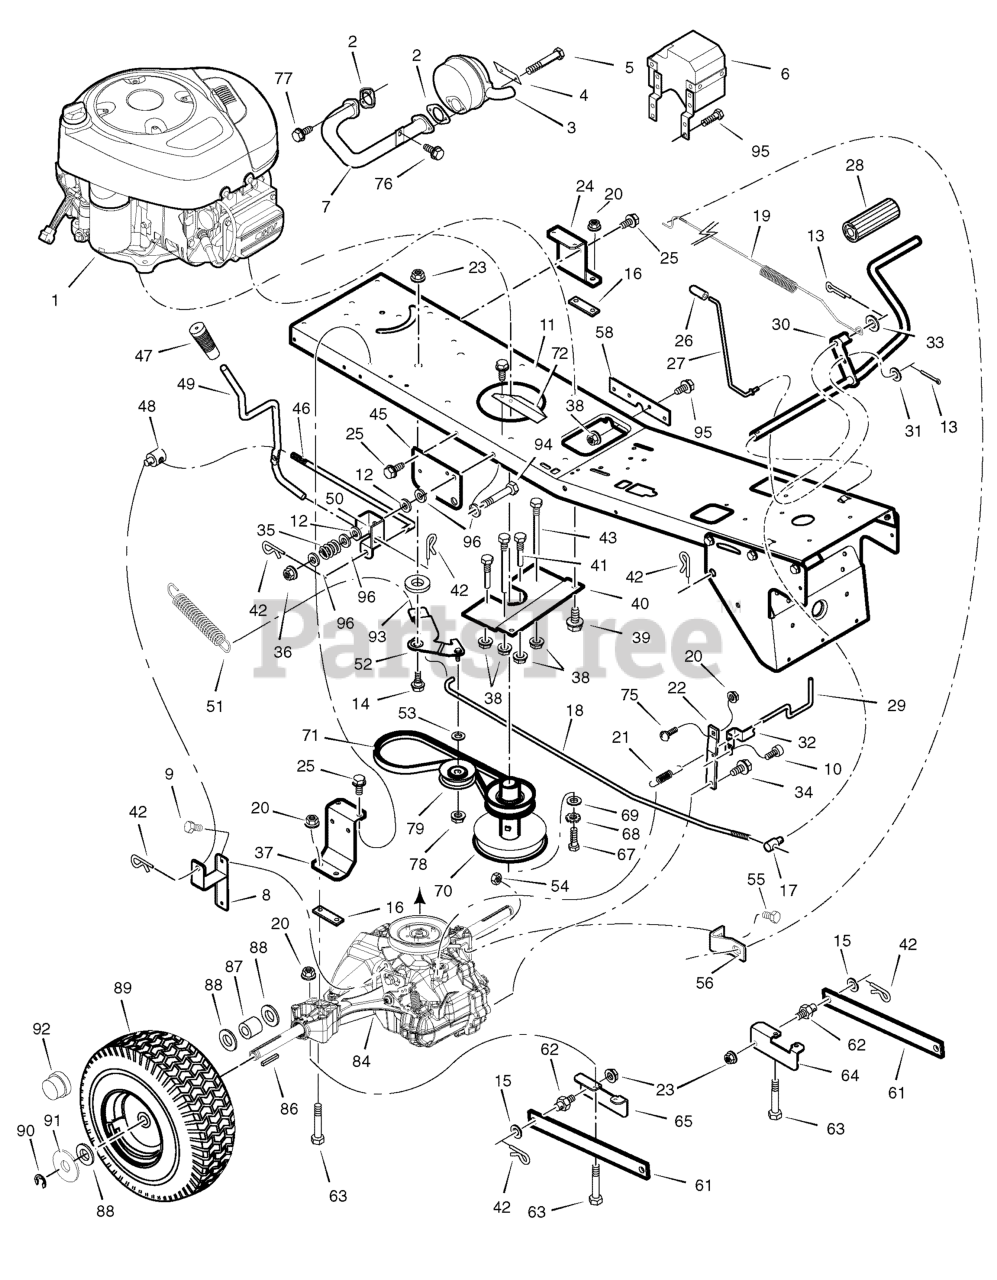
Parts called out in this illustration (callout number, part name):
1	ENGINE, Briggs & Stratton *
2	GASKET, Exhaust
4	LOCK, Muffler Screw
5	BOLT, Hex
6	SHIELD, Heat
7	TUBE, Exhaust
8	BRACKET, Shift Lever Weldment
9	BOLT, Hex
10	SCREW
11	FRAME
13	PIN, Cotter
14	BOLT, Shoulder
16	PLATE, Transaxle
17	NUT, Adjusting
18	ROD, Clutch Hydro
19	SPRING, Brake
20	NUT
21	SPRING, Roll Release
22	BRACKET, Torque
23	NUT
24	BRACKET, Left Transaxle
27	ROD, Parking Brake
28	PEDAL
29	ROD, Roll Release
30	ROD, Clutch/Brake
32	BRACKET, Roll Release
33	WASHER
35	Spring, Compression
37	BRACKET, Right Transaxle
38	NUT
39	SCREW
40	PLATE, Belt Guide
41	GUIDE, Belt, Long
42	PIN, Hair
43	GUIDE, Belt, Short
45	BRACKET, Lift Pivot
46	ROD, Shift Link
48	NUT, Adjusting
49	LEVER, Shift
50	BRACKET, Pivot
51	SPRING, Variator Drive
52	ARM, Idler
54	NUT, 5/16-18
55	SCREW, Hex
56	BRACKET, Brake Spring Extension
58	PLATE, Reinforcement
62	PIN, Threaded
63	BOLT, Hex
64	BRACKET, Left Rear Hanger
65	BRACKET, Right Rear Hanger
67	BOLT, Hex
68	LOCKWASHER
70	PULLEY STACK
71	BELT, Drive, 4L
72	HEAT SHIELD
75	BOLT, Carriage
78	LOCKNUT
79	PULLEY, Idler
84	TRANSAXLE **
86	KEY, Square
87	SPACER, Rear Wheel
89	WHEEL & TIRE ASSEMBLY
92	HUB CAP
94	BOLT, Hex
96	WASHER, Delrin
